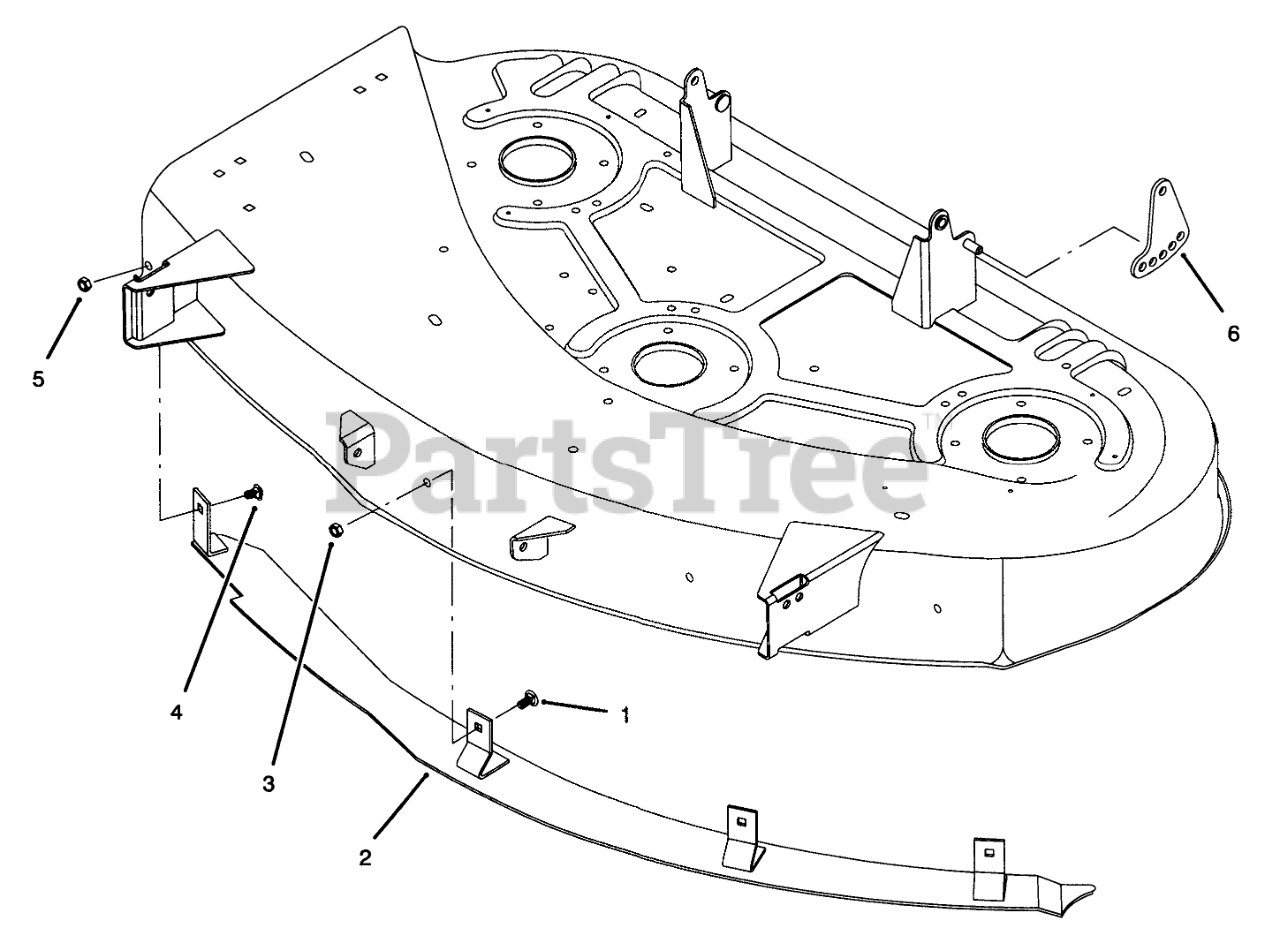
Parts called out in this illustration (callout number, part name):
1	SCREW-CARR
2	BAFFLE WA BLACK (NS)
3	NUT-LOCK, NI
4	SCREW-CARR
5	NUT-LOCK, NI
6	LINK - HOC ADJUSTING
